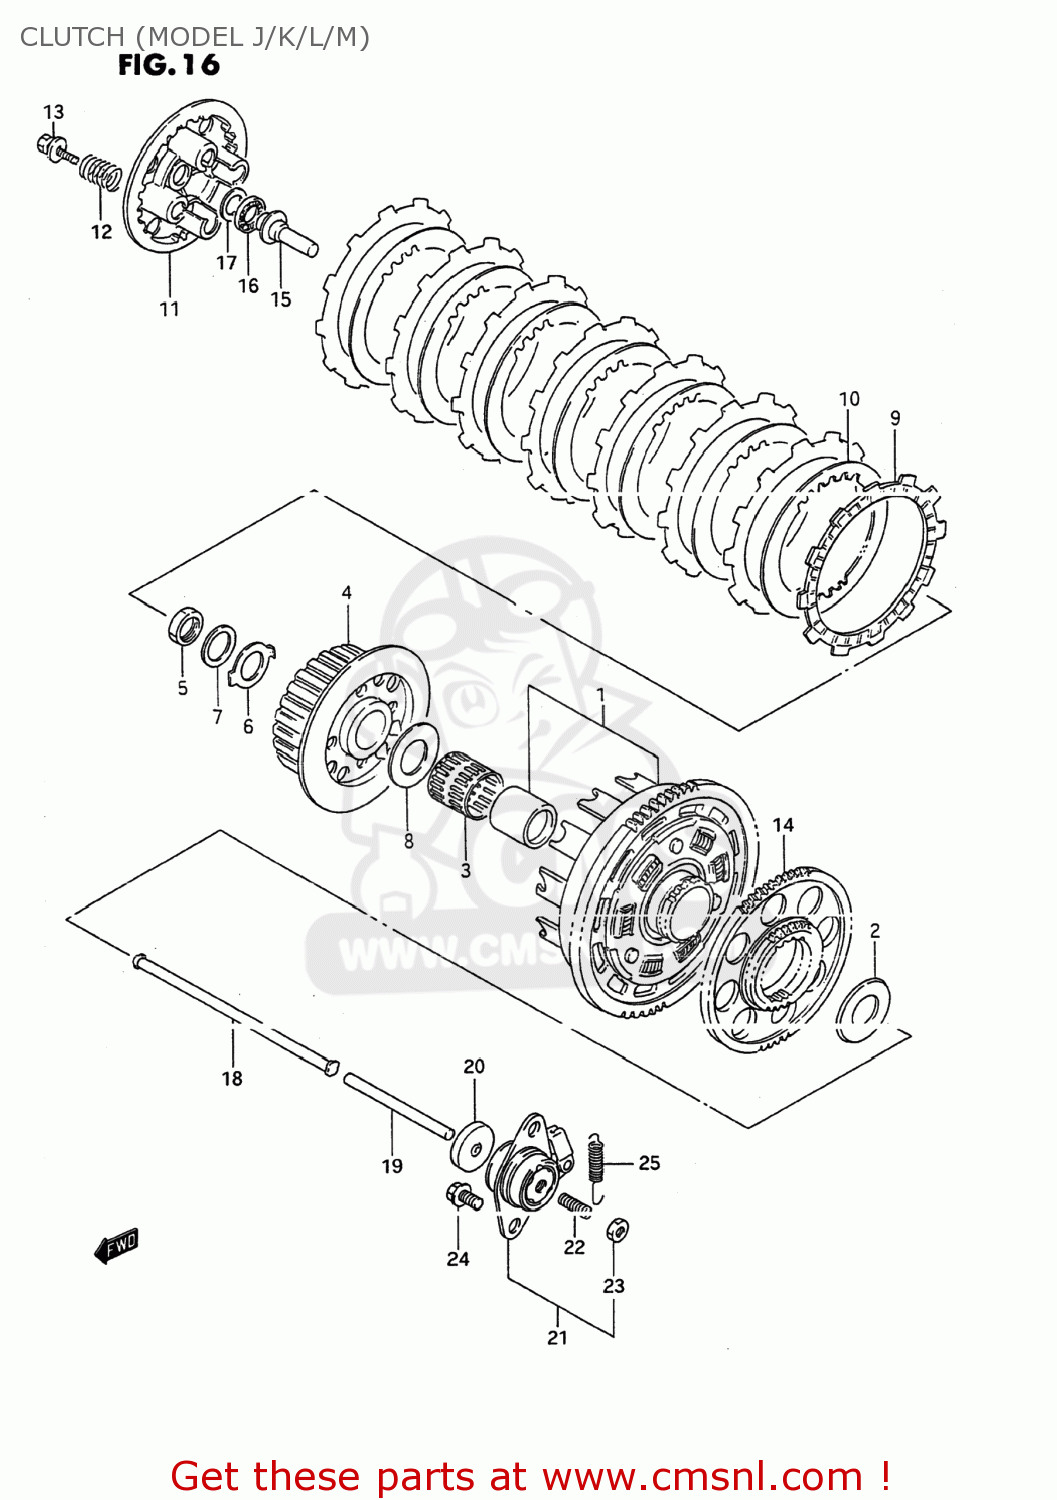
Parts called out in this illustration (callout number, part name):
1	GEAR ASSEMBLY,PRIMARY DRIVE
2	WASHER(25X54X2.5)
3	BEARING(35X40X35.8)
4	HUB,CLUTCH SLEEVE
5	NUT
6	WASHER
7	WASHER
8	WASHER(25X50X2.5)
9	PLATE,CLUTCH DRIVE (NAS)
10	PLATE,CLUTCH DRIVEN (NAS)
11	DISC,CLUTCH PRESSURE
12	SPRING
13	BOLT
14	GEAR,GENERATOR DRIVE
15	PIECE,CLUTCH PUSH
16	BEARING(15X28X2)
17	WASHER
18	ROD,CLUTCH PUSH
19	ROD,CLUTCH PUSH,L
20	SEAL,OIL(6X34X5.5)
21	SCREW ASSY,CLUTCH RELEASE
22	SCREW(6X25)
23	NUT 6MM
24	BOLT
25	SPRING
